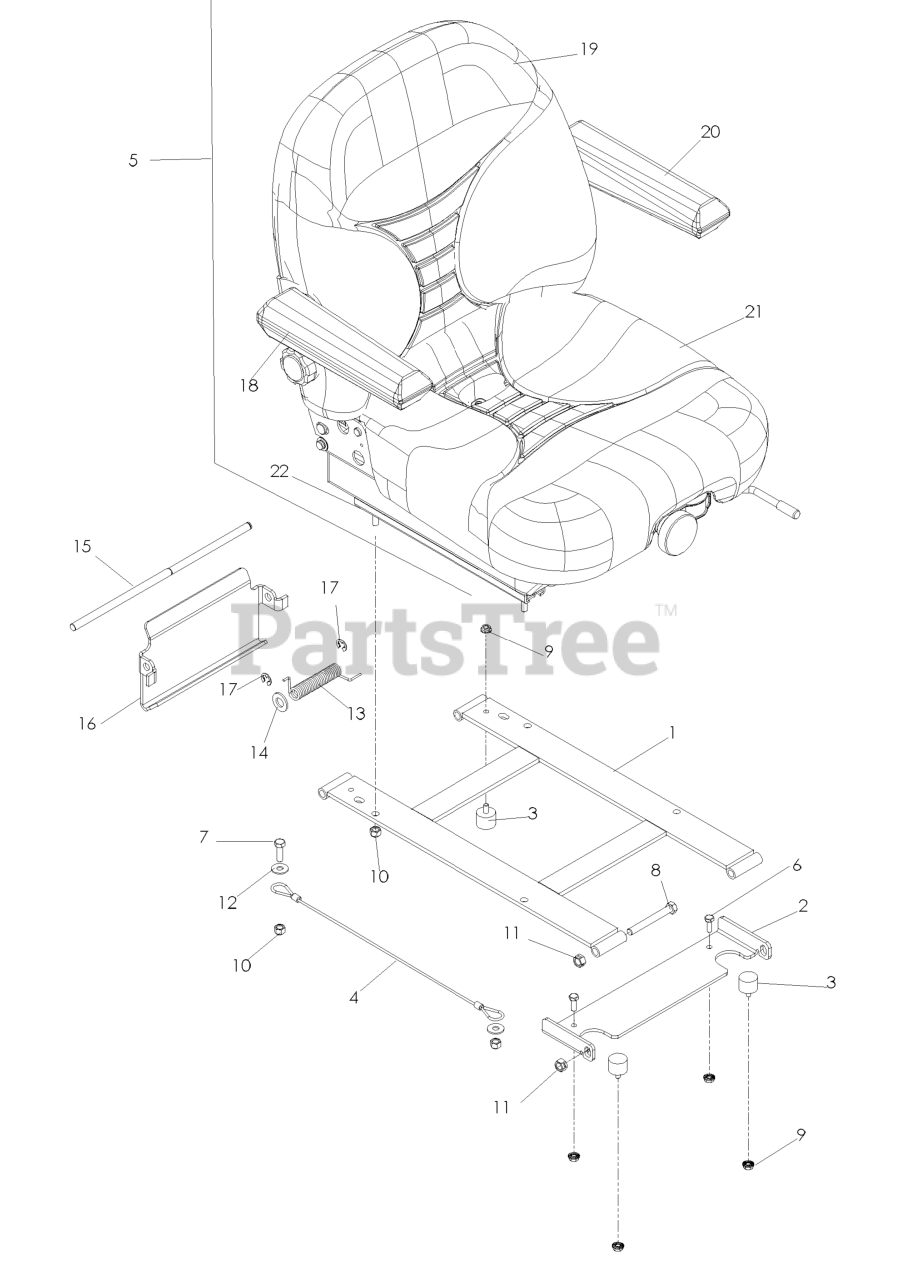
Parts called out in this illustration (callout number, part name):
1	SEAT MOUNT WLDMT
2	SEAT BKT. W/PAINT
3	STUD/PLATE MOUNT
4	SEAT LANYARD
5	SEAT, SUSPENSION
6	HCS 1/4C X 3/4 HCS
7	HCS 5/16C X 1
8	HCS 3/8C X 3
9	NUT 1/4-20 HEX FLG LK ZD
10	NUT 5/16 NYLOC
11	NUT 3/8C CENTERBLOCK
12	WASHER 5/16 FLAT
13	TORSION SPRING (SEAT)
14	WASHER 3/8 SAE FLAT
17	E RING 3/8"
18	ARMREST KIT, RH
19	BACK CUSHION KIT
20	ARMREST KIT, LH
21	SEAT CUSHION KIT
22	SLIDE KIT, SEAT ADJ
